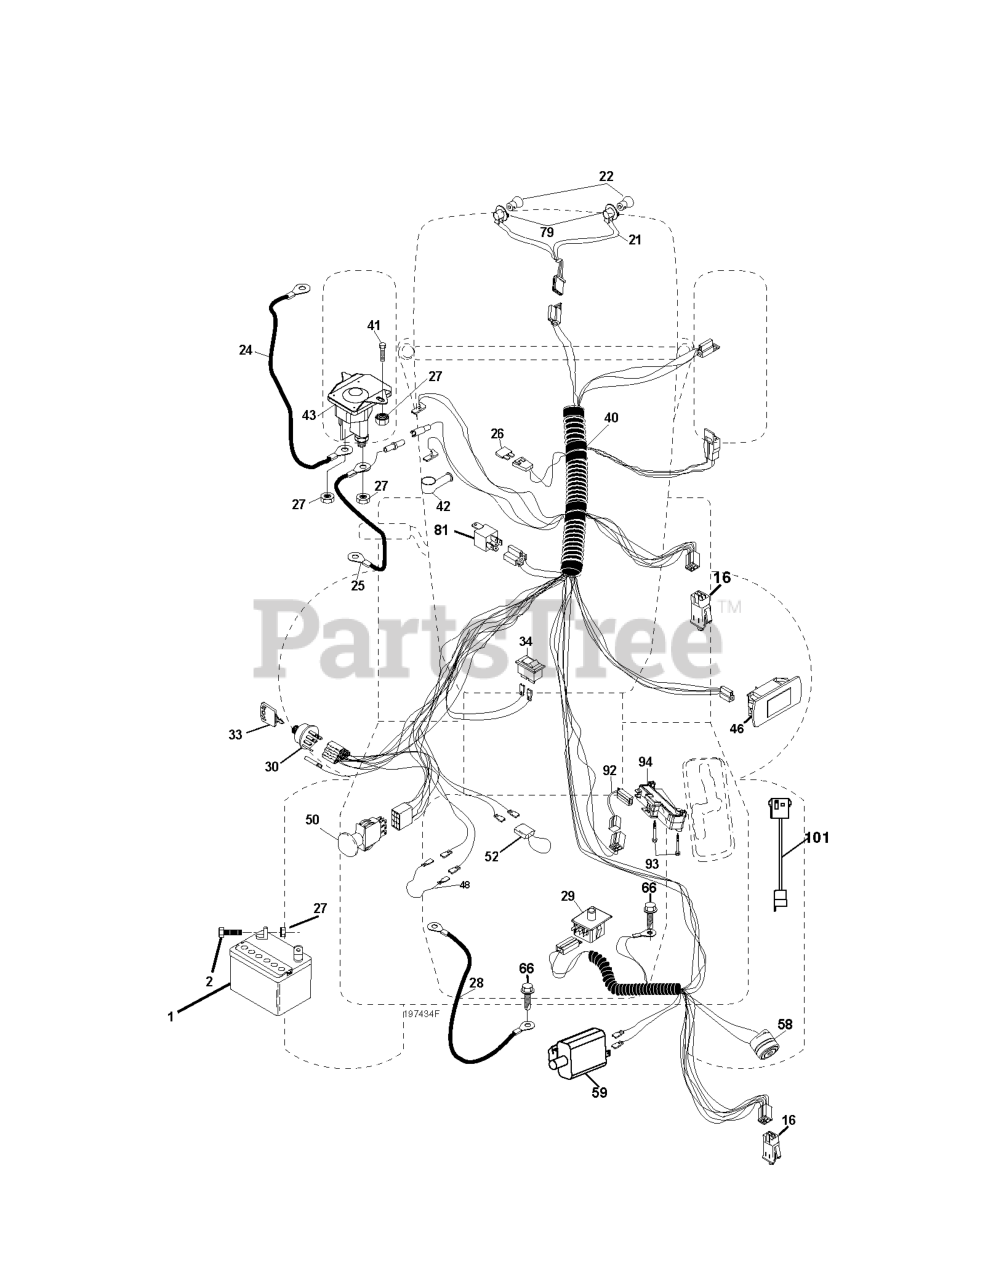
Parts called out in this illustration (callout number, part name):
1	BATTERY 12V .35 AMP
2	BOLT.HEX.1/4.X.3/4.DICHROMATE
16	SWITCH INTERLOOK PUSH-IN
21	HARNESS.LIGHT W/4152J BULBS
24	BATTERY CABLE GT
25	CABLE BATTERY
26	FUSE 20AMP
27	NUT
28	CABLE GROUND
29	SWITCH.SEAT.DP W/RAMPS
30	SWITCH.IGN.DELTA.W.LGH.ROS
33	KEY MLD GEN DELTA
40	RP HARNESS.IGN.ELECT.REG.CRD
41	BOLT
42	TERMINAL COVER
43	SOLENOID.W/BRASS.PLUNGER
46	PLUG DASH
48	ADAPTER.AMMETER
50	RP.PTO.SWITCH.8 TERMINAL.BLACK
52	WIRE PROTECTION LOOP
58	BUZZER
59	.WITCH.FULL BAGGER.INDICATOR
79	BULB HOLDER ASM.
81	RELAY.ASSY.T
92	HARNESS.PIGTAIL.CONSLE
93	SCREW.PLASTITE
94	MODULE.REVERSE.ROS
101	PIGTAIL.MATNLK.NEW.HAR
